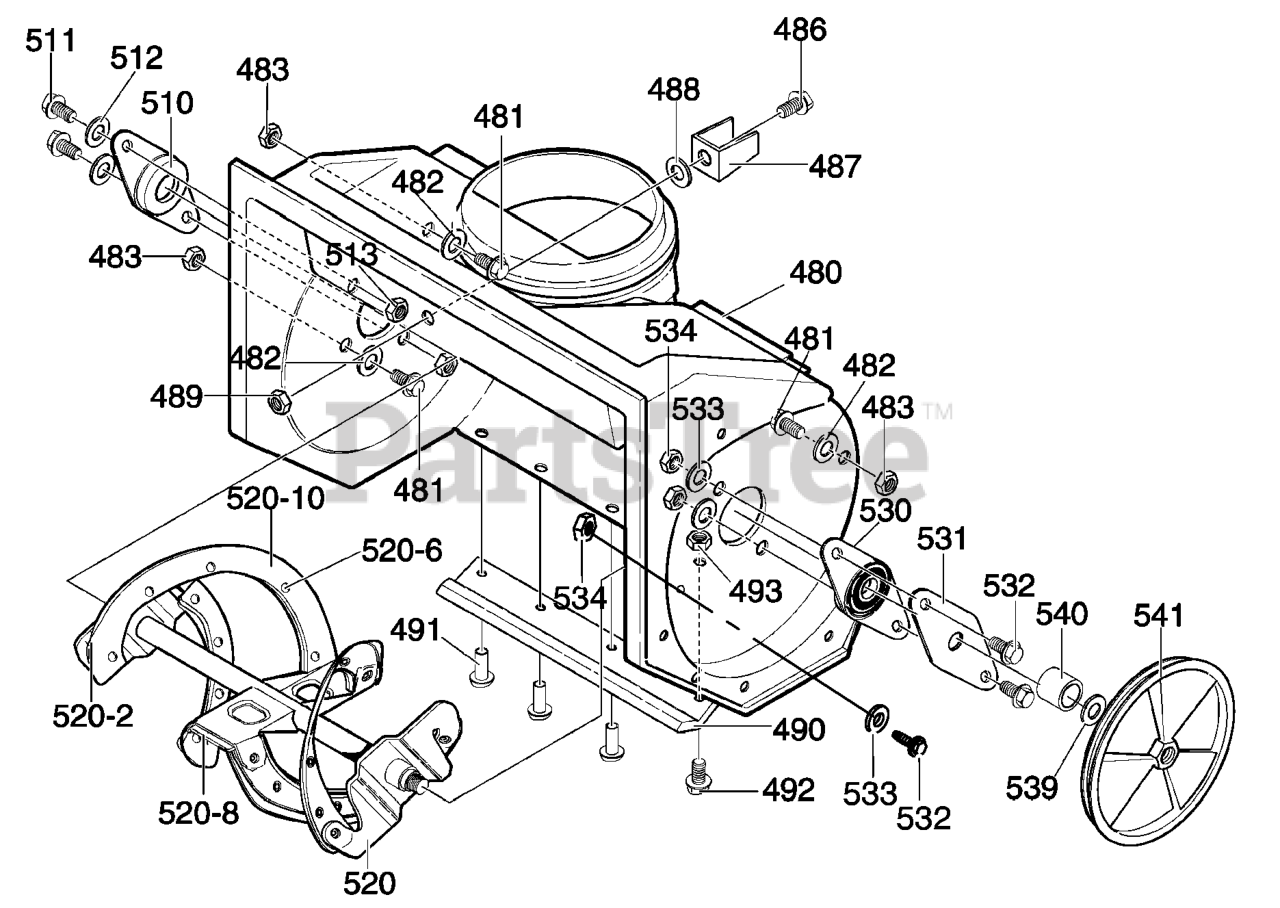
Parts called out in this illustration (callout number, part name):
480	HOUSING ASSEMBLY
481	SCREW, 1/4-20x.75
482	FLATWASHER
483	NUT, 1/4-20
486	SCREW, 1/4-20 x.63
487	BRACKET, STOP
488	FLATWASHER
489	NUT,1/4-20
490	SCRAPER BAR
491	RIVET
492	SCREW, 1/4-20x .75
493	NUT, 1/4-20
510	FLANGE BEARING
511	SCREW, 1/4-20x1.00
512	FLATWASHER
513	NUT, 1/4-20
520	AUGER ASSEMBLY
520-2	AUGER BLADE
520-6	RIVET
520-8	CENTER BLADE
520-10	AUGER & BLADE SUPPORT
530	BEARING & PLATE ASSY.
531	BEARING RETAINER
532	SCREW, 1/4-20x5/8
533	FLATWASHER,.281x.63x.065
534	NUT, 1/4-20 Reghexctrlk
539	FLATWASHER
540	SPACER, SLEEVE
541	PULLEY, POLY V -AUGER
